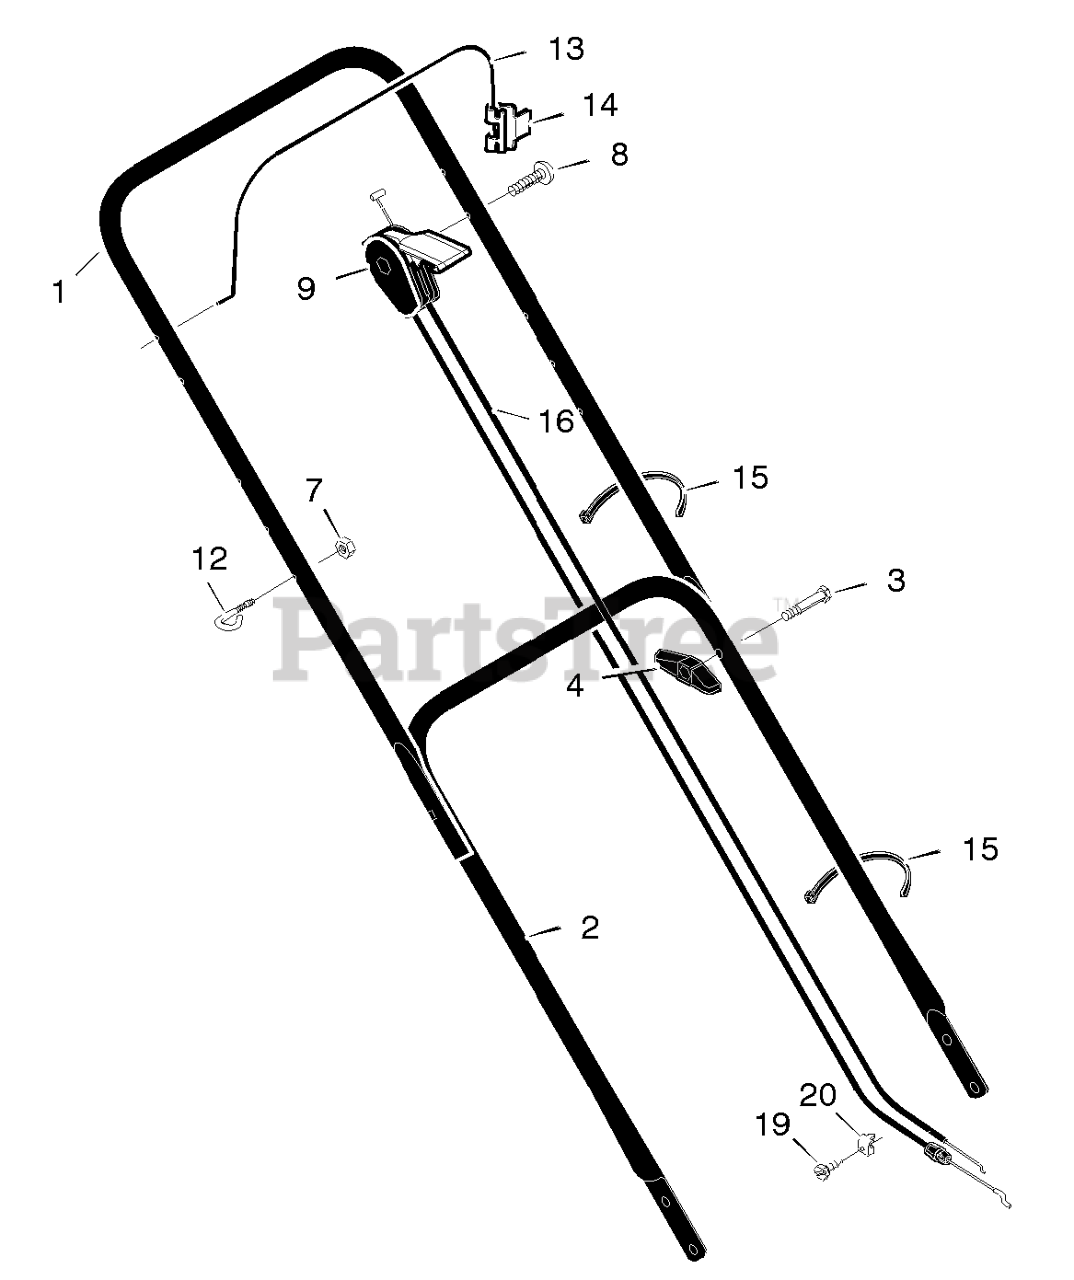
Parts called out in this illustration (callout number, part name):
1	Handle, Upper (Black)
2	Handle, Lower (Black)
4	Knob, Plastic
7	Locknut
9	Throttle Control
12	Guide, Rope
13	Engine Stop Lever
14	Bracket, Stop Lever
15	Fastener, Cable
16	Engine Stop Cable
